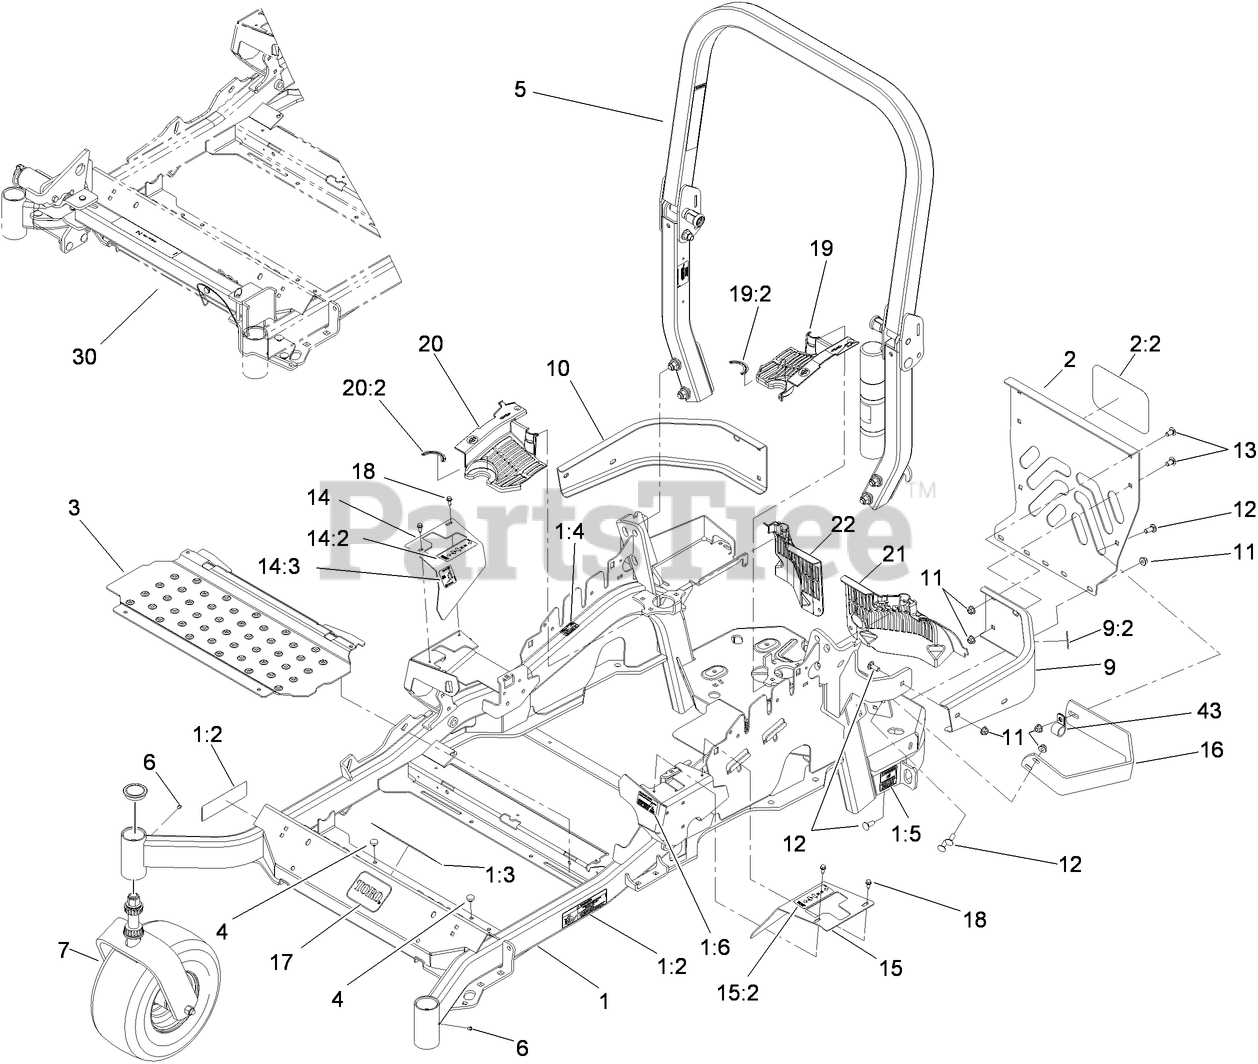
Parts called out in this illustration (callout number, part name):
1	MAIN FRAME ASM
1:2	DECAL-CAUTION
1:3	DECAL-SLOPE
1:4	DECAL-BELT DRIVE
1:5	DECAL-ARRESTER, SPARK
1:6	DECAL-FUEL FILL
2	REAR GUARD ASM
2:2	DECAL
3	FLOORPAN
4	BUMPER
5	ROPS ASM
7	Caster Wheel ASM
9	BUMPER-REAR, LH
9:2	DECAL-CAUTION
10	BUMPER-RH
11	NUT-HF, NI
12	SCREW-CARR
13	SCREW-CARR
14	RH MOTION CONTROL COVER ASM
14:2	DECAL-MOTION CONTROL
14:3	DECAL-PARK BRAKE
15	LH MOTION CONTROL COVER ASM
15:2	DECAL-MOTION CONTROL
16	GUARD-MUFFLER
17	DECAL
18	SCREW-HWH
19	LH HYDRO GUARD ASM
19:2	DECAL-HYDRO OIL
20	RH HYDRO GUARD ASM
20:2	DECAL-HYDRO OIL
21	GUARD-HYDRO, REAR (LH)
22	GUARD-HYDRO, REAR (RH)
30	Z STAND ASM
43	CLIP-LOOM
